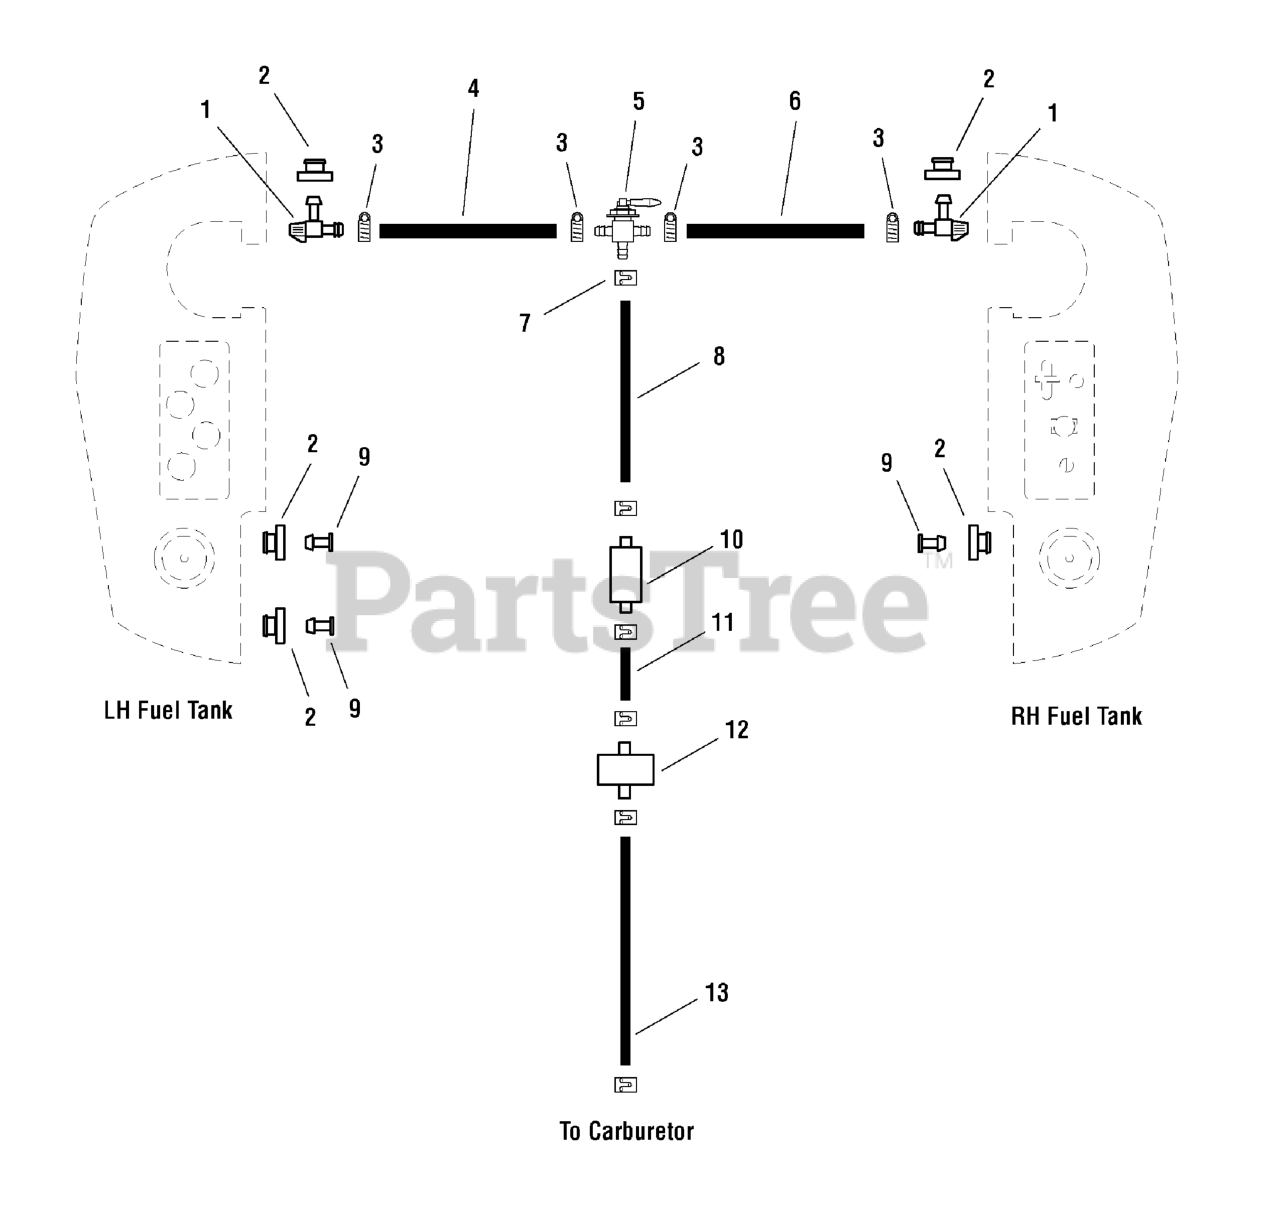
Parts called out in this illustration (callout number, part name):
1	VALVE, Fuel Shut-Off
2	BUSHING-FUEL TANK RED RUBBER
3	CLAMP, #4 Hose
4	HOSE, 34"
5	FUEL SHUT OFF VALVE
6	HOSE, 46"
7	CLAMP, Hose
8	1/4" Fuel Line, 30" Long
9	PLUG
10	FUEL FILTER
11	1/4" Fuel Line, 12" Long
12	FUEL PUMP
13	1/4" Fuel Line, 36" Long
